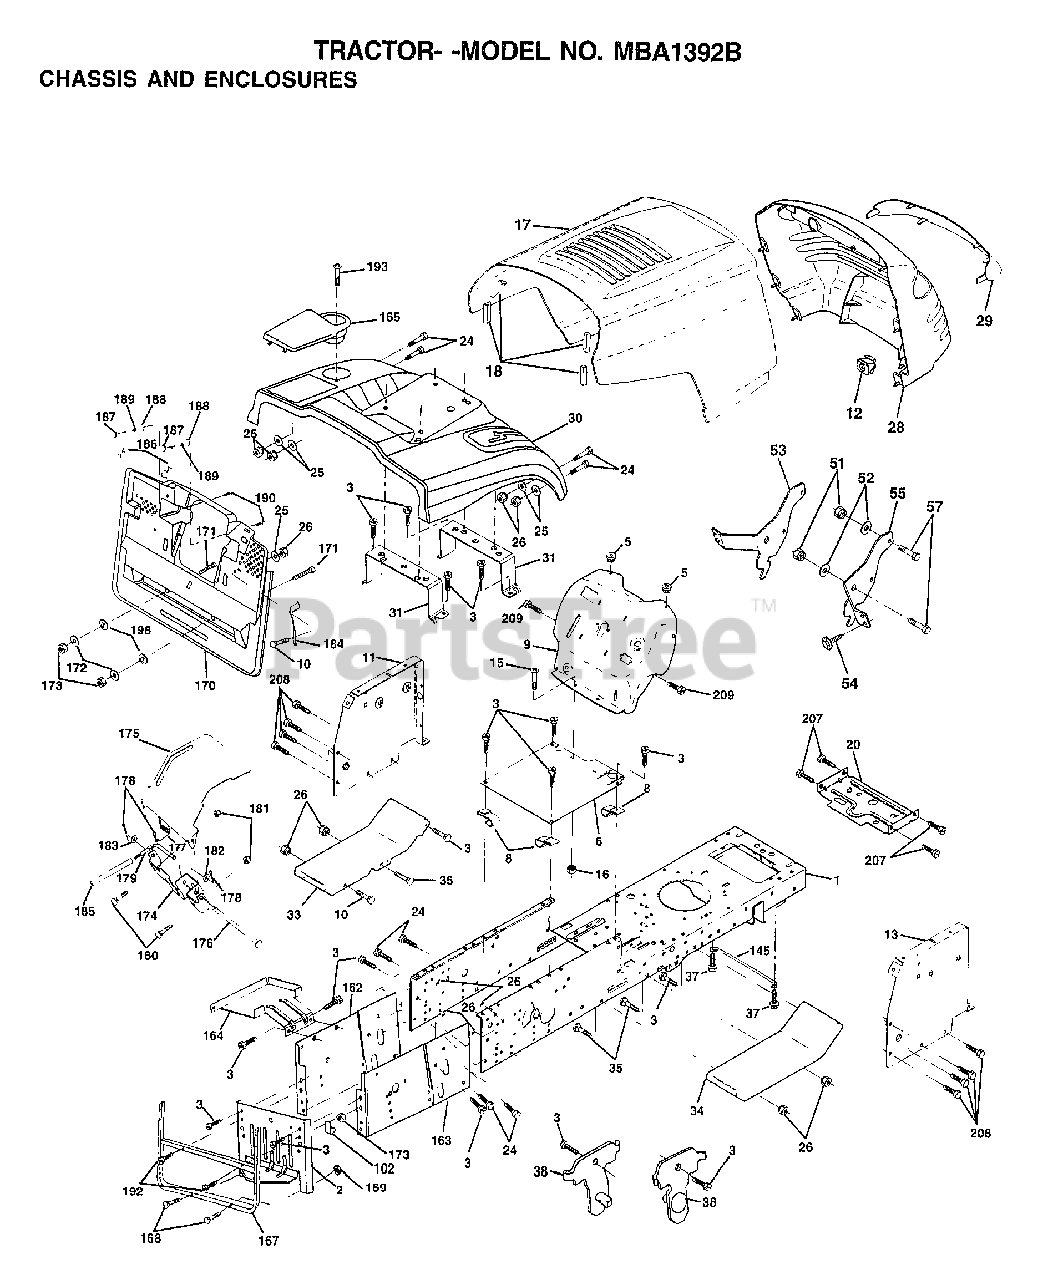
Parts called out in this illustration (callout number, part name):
2	DRAWBAR.CRD
3	SCREW
5	BUMPER-HOOD/DASH
6	SADDLE
8	"CLIP,INSULATOR"
9	DASH
11	"PANEL-DASH,LH"
12	CLIP.TINNERMAN
15	SCREW
17	HOOD.PNT.W/TRIM
20	"PLATE-MTG,BATT/FU"
24	BOLT
25	WASHER
26	NUT
28	GRILLE
29	LENS.GRILLE
31	BRKT.SUPT.FENDER.CRD
33	FOOTREST.LH.YT/GT
34	FOOTREST.RH.LT/YT
35	BOLT
37	SCREW LT
38	BRKT ASM PIVOT MOWER REAR
51	NUT
52	WASHER
53	BRACKET.GRILLE.LH
54	SCREW.HEX.WS.HD
55	BRACKET.GRILLE.RH
102	CLIP T
145	"ROD POVOT,CHASSIS"
162	BRKT.EXT.CHASSIS.LH.CRD
163	BRKT.EXT.CHASSIS.RH.CRD
164	SUPPORT.BATTERY.CRD
165	COVER.BATTERY.CRD.BLACK.LT
167	SUPT.ASM.BACKPLATE
168	BOLT-RD HD SQ NK
170	COVER.BACKPLATE.BLACK
171	BOLT.HEX.3/8-16X2-1/2
173	NUT
174	BRKT.SWITCH.FBI.CRD
175	GRUARD.DOOR.REAR.CRD
176	HINGE PIN
177	SPRING.COVER.LH
179	ROD.PIVOT.FBI.CRD
182	WASHER.385X.625
183	WASHER
184	BRKT.ACTUATOR.BAG.CRD
185	TUBE.LEVER.SWCH.FBI.CRD
186	LATCH ASSY.BAGGER
187	WELDNUT
188	WASHER #10
189	LOCKWASHER
190	SCREW
192	SCREW LT
193	SCREW
198	NUT PUSH
207	SCREW
208	SCREW
209	SCREW
